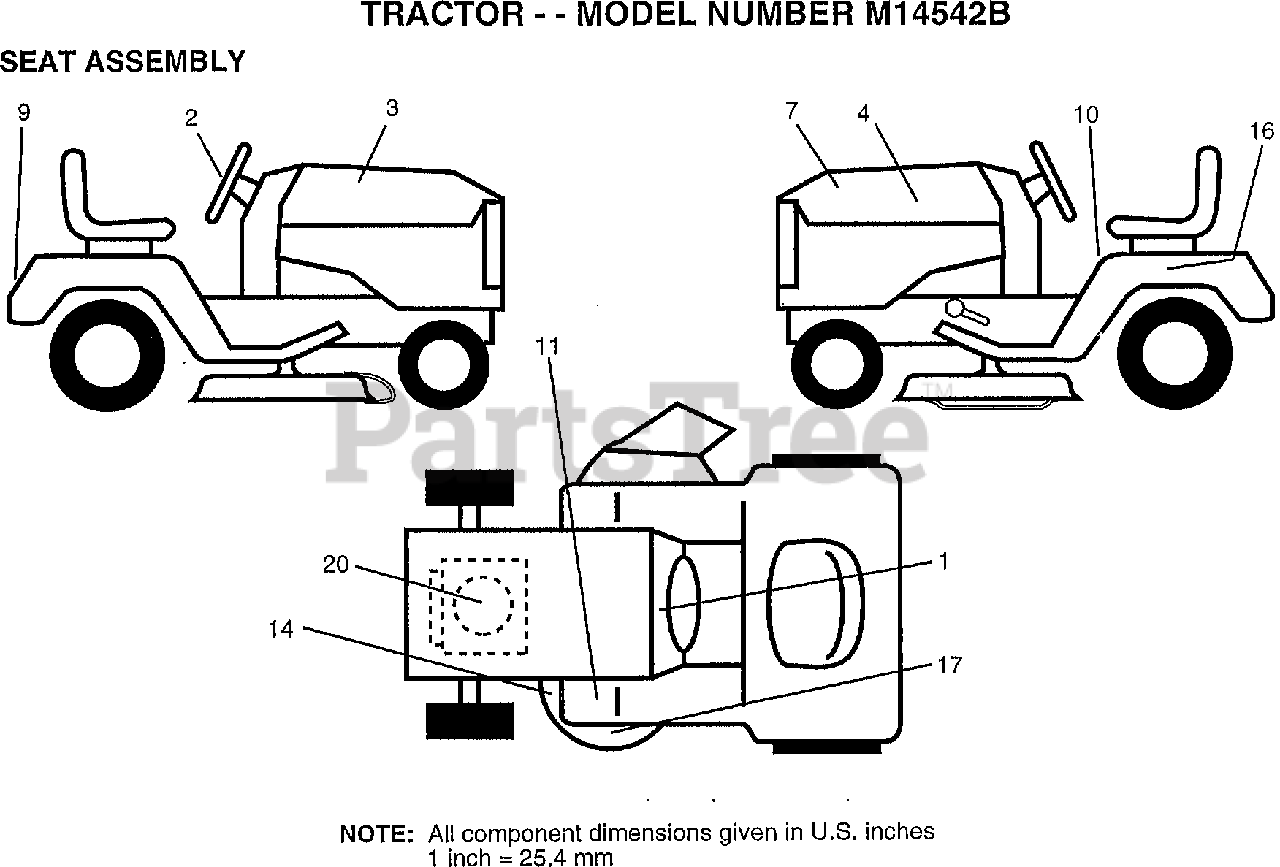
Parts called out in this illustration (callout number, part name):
1	"DECAL DASH,OPER."
2	"DECAL INS,STRG WH"
3	DECAL HOOD RH
4	"DECAL HOOD,LH"
7	"DECAL PANEL,SIDE"
9	"DECAL FENDER,MEIJ"
10	"DECAL DANGER,FEND"
14	DECAL
16	DECAL.BATRY.3-3908
17	"DECAL,ENVIRO DECK"
20	DECAL, ENGINE
